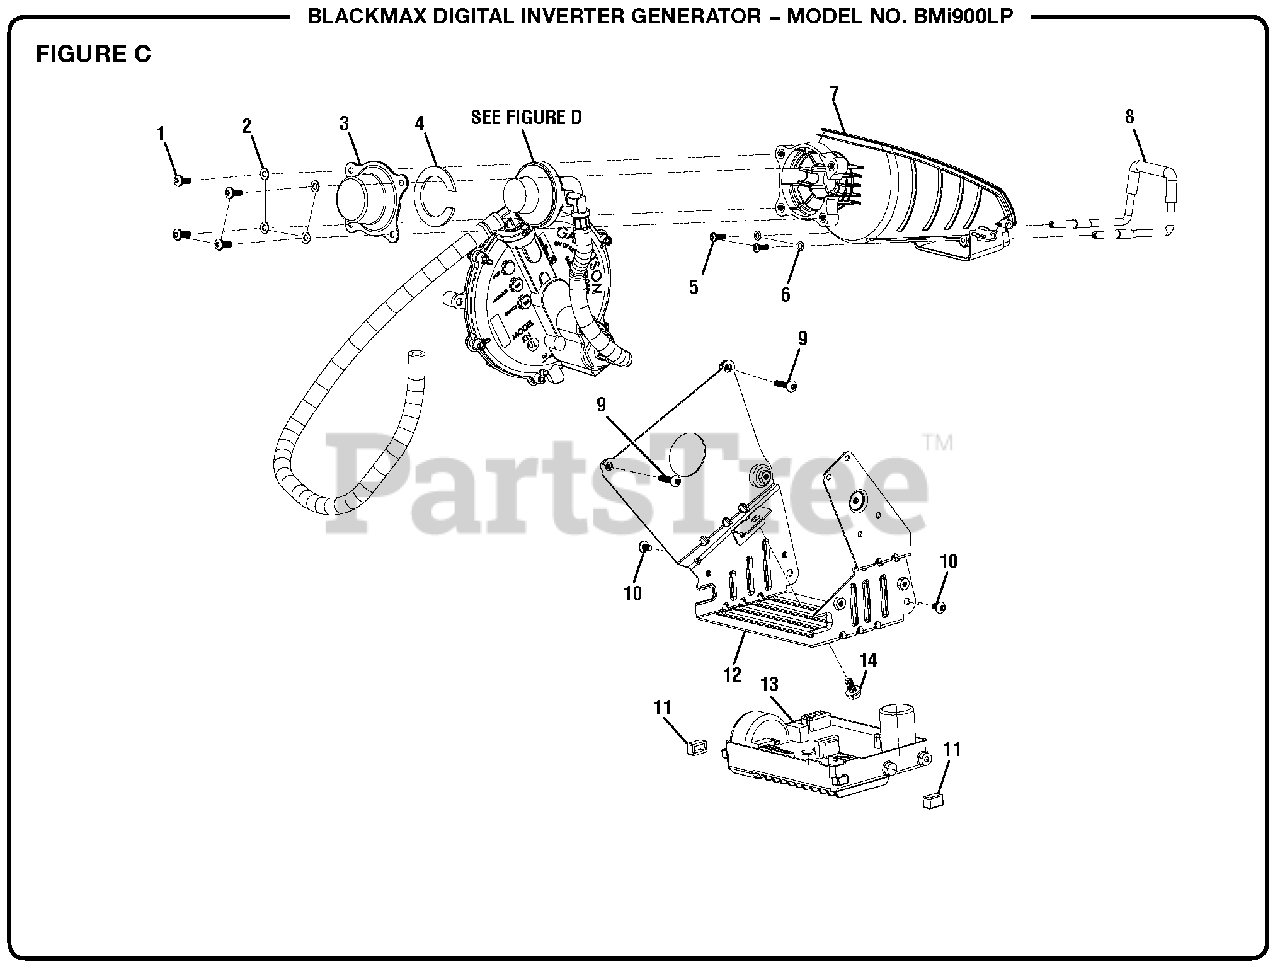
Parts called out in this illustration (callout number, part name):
1	Screw (M5 x 12 mm, T-25 Torx Pan Hd.)
2	Washer (ID5.2 x OD10 x 1t)
3	Metal Cover
4	Rubber Pad
5	Screw (M4 x 12 mm, T-20 Torx Pan Hd.)
6	Washer (ID4.5 x OD8 x 0.5t)
7	1LP Tank Assembly
8	Metal Tube
9	Screw (M5 x 22 mm, T-25 Torx Pan Hd.)
10	Screw (M5 x 8 mm, T-25 Torx Pan Hd.)
11	Rubber Support
13	Inverter Module (700W)
14	Bolt (1/4 in. x 20-1/2 in., Flanged Hex Hd.)
